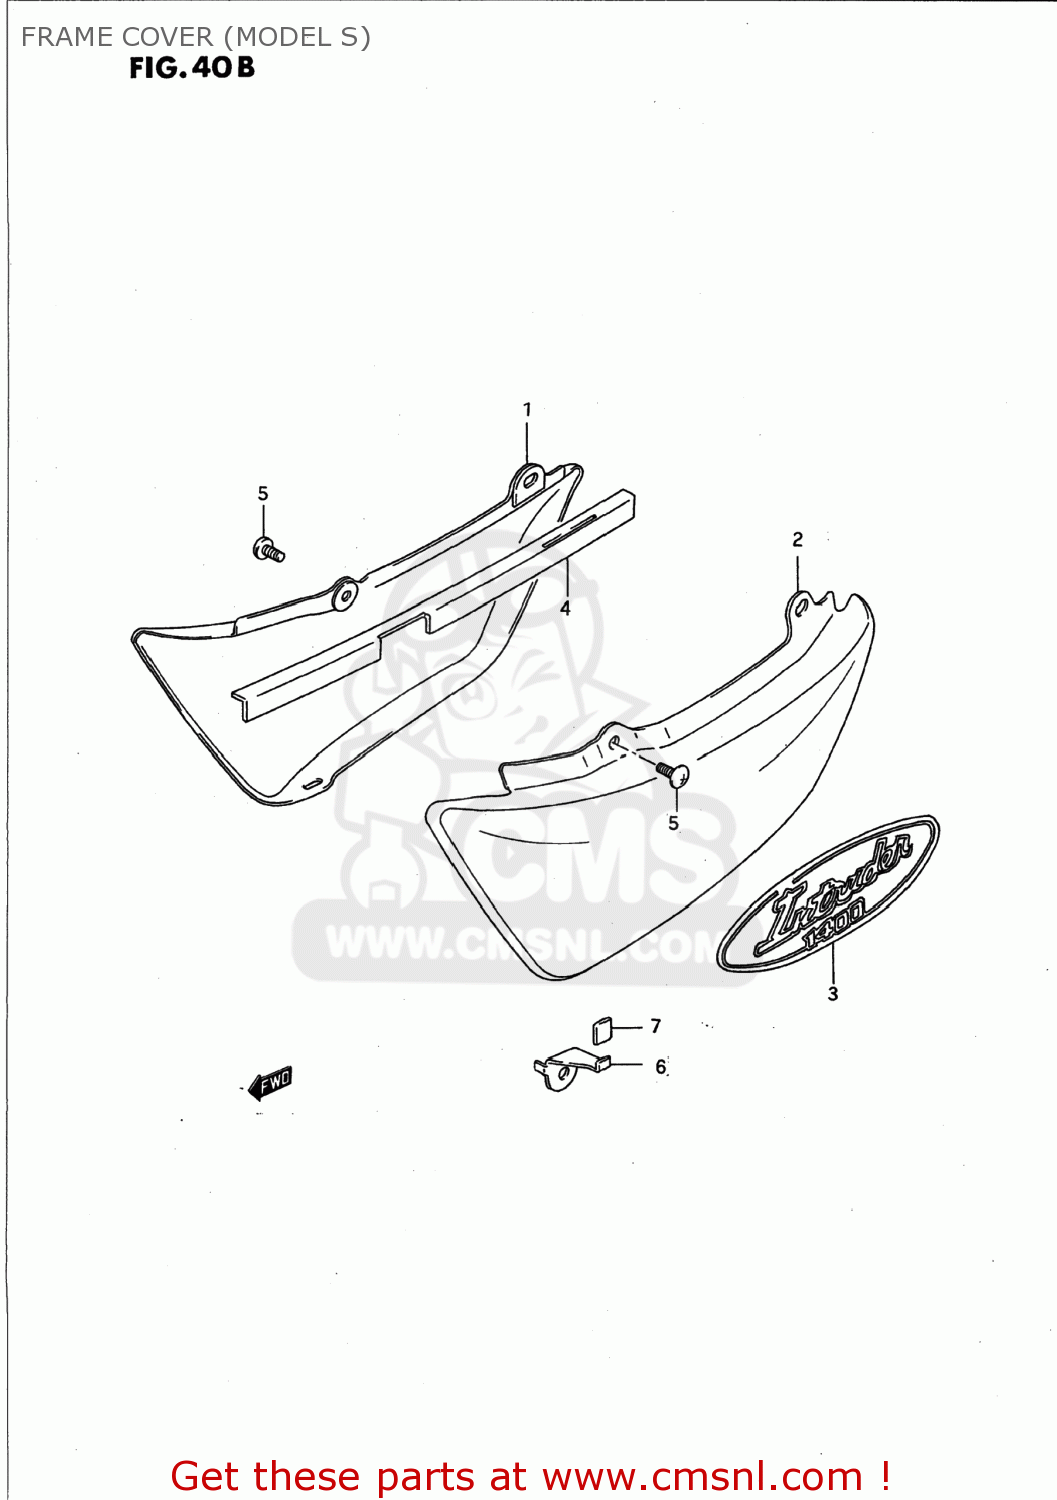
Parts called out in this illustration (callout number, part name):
1	1-2
2	COVER,FRAME,L(GREEN)
3	EMBLEM,FRAME COVER
4	PROTECTOR,FRAME COVER,R
5	SCREW 6X12
6	HOOK,FRAME COVER,L
7	CUSHION,FRAME COVER HOOK
